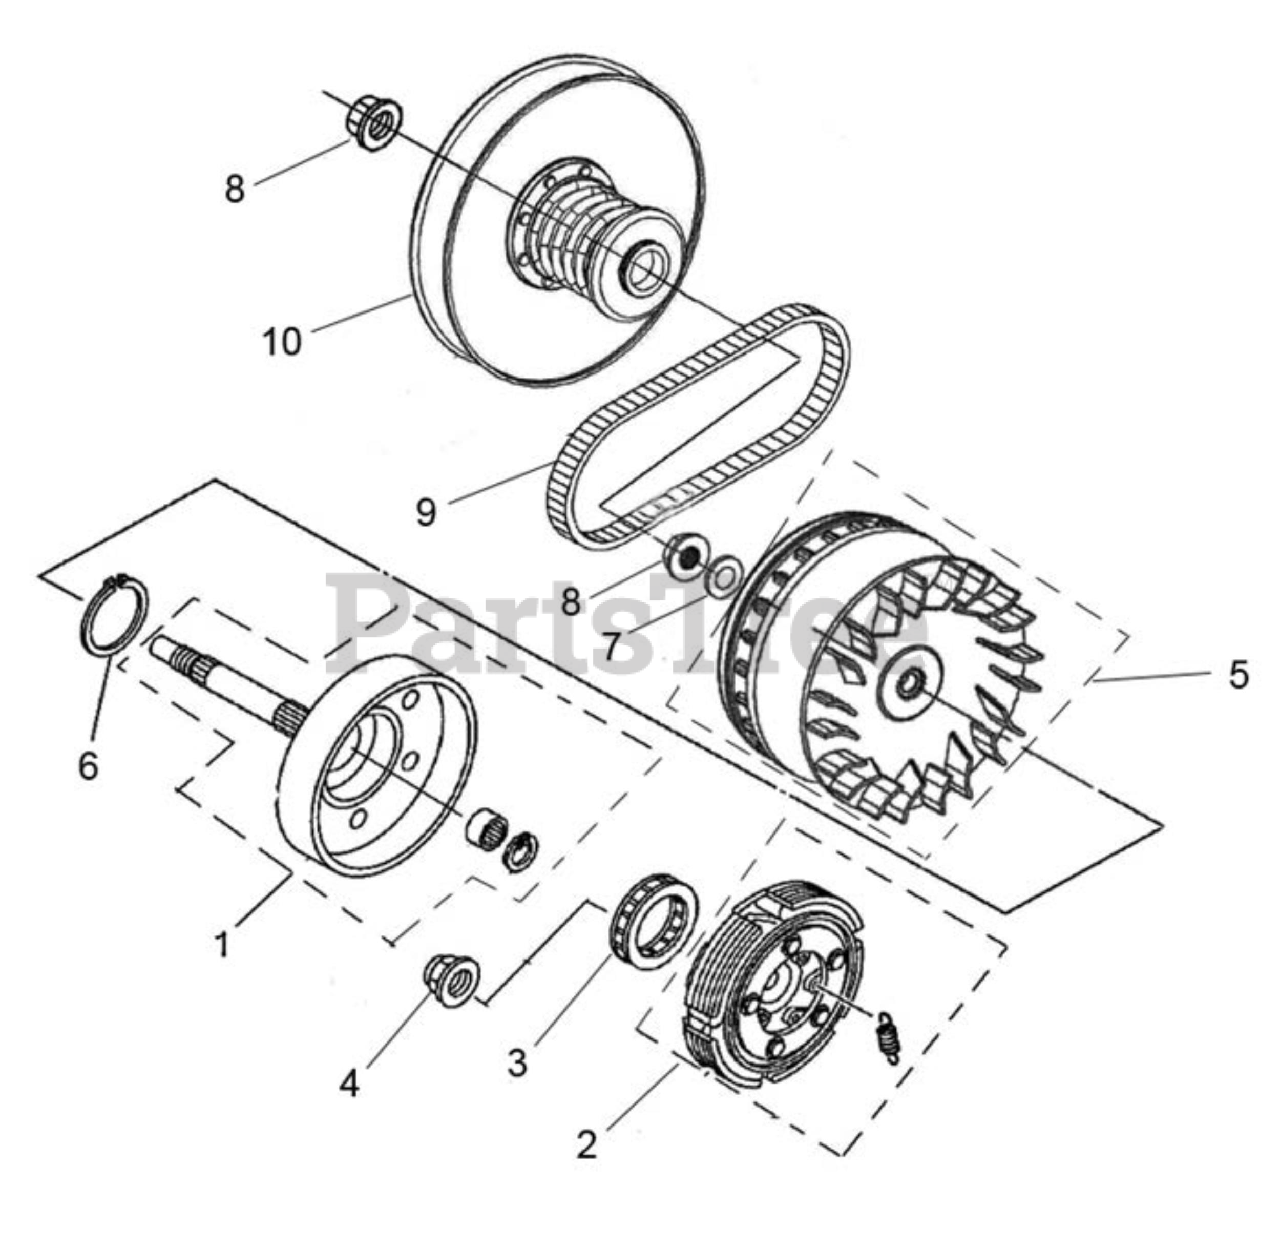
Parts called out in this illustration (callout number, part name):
1	Friction Wheel Assy,Clutch
2	Friction Plate Assy,Clutch
3	Overrunning Clutch Assy
4	Hexagon Flange Nut M22X1
5	Primary Disc Assy
6	Circlip for shaft 52
7	Washer 19.2X35X3.2
8	Hexagon Flange Nut M16X1
10	Driven Pulley Assy
